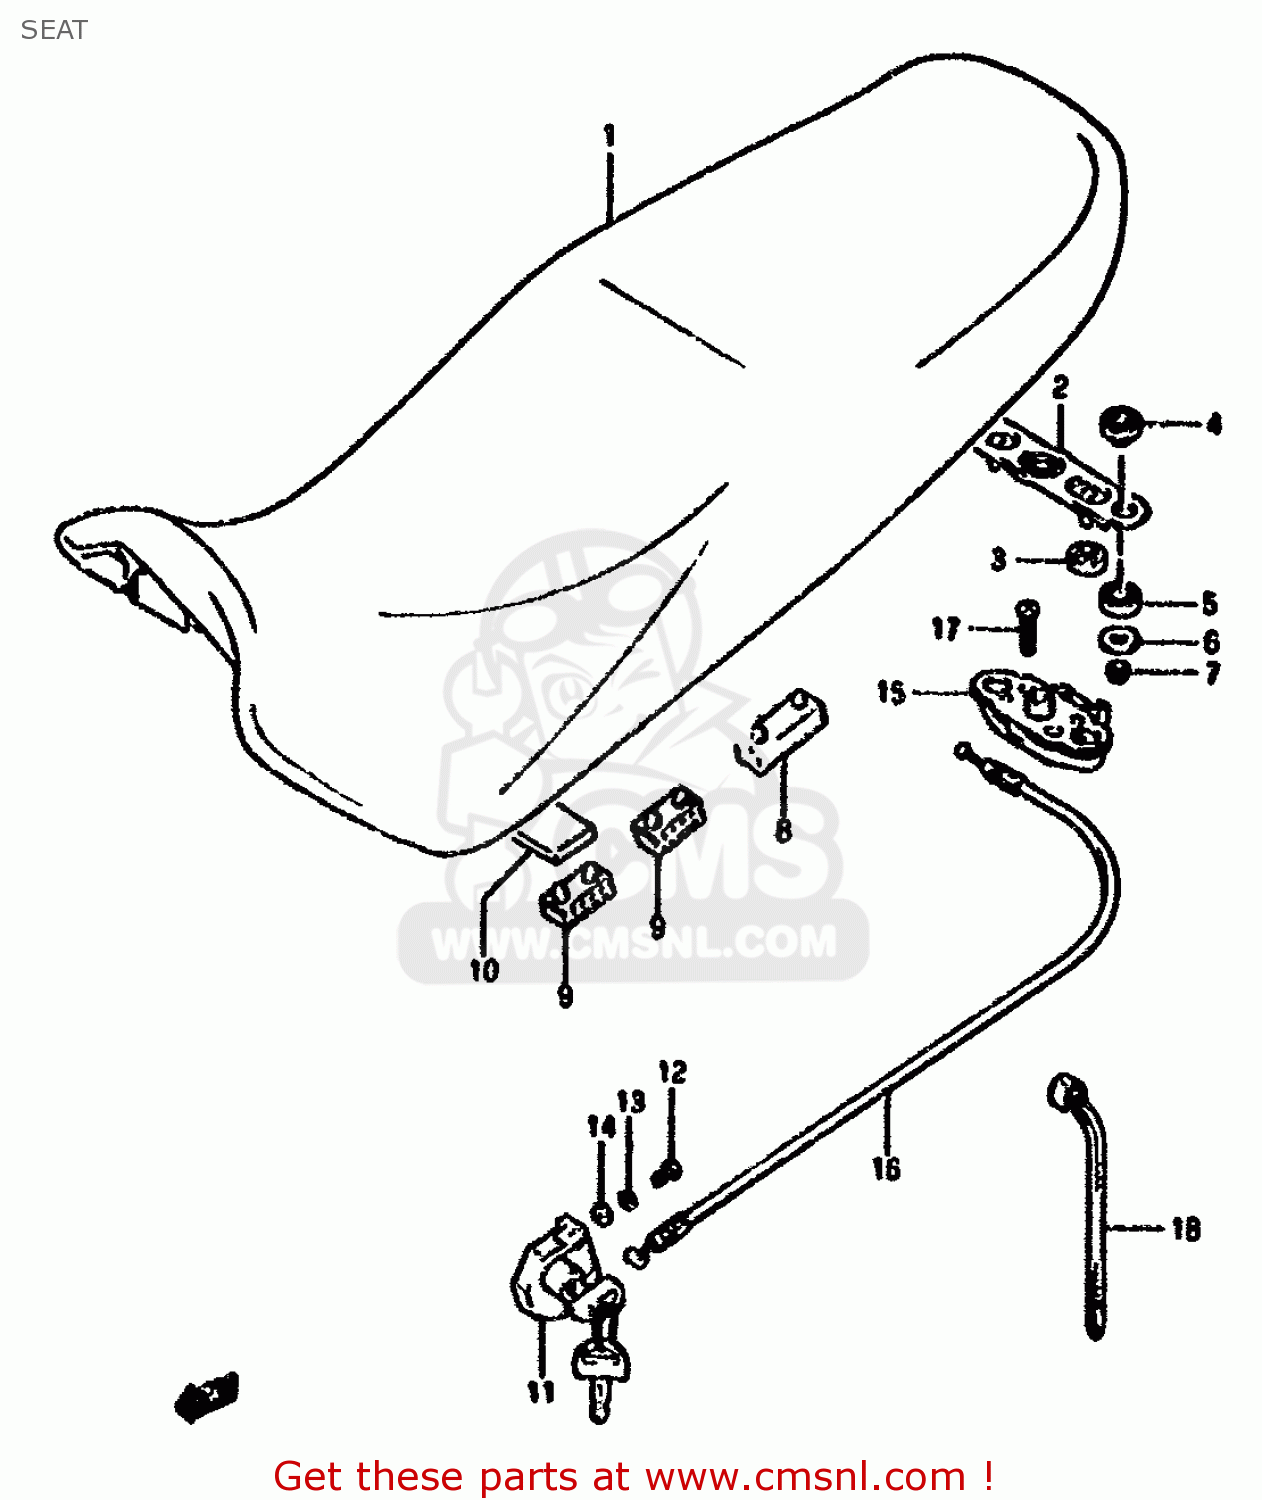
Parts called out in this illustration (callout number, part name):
1	SEAT ASSEMBLY
2	STRIKER,SEAT LOCK
3	CUSHION
4	CUSHION
5	CUSHION
6	WASHER
7	NUT
8	CUSHION,SEAT
9	CUSHION,SEAT
10	CUSHION(30X60X10)
11	LOCK SET
12	SCREW
13	WASHER,LOCK
14	WASHER,5MM
15	BRACKET,SEAT SUPPORT,RIGHT
16	CABLE,SEAT LOCK
17	SCREW
18	CLAMP(L:125)
